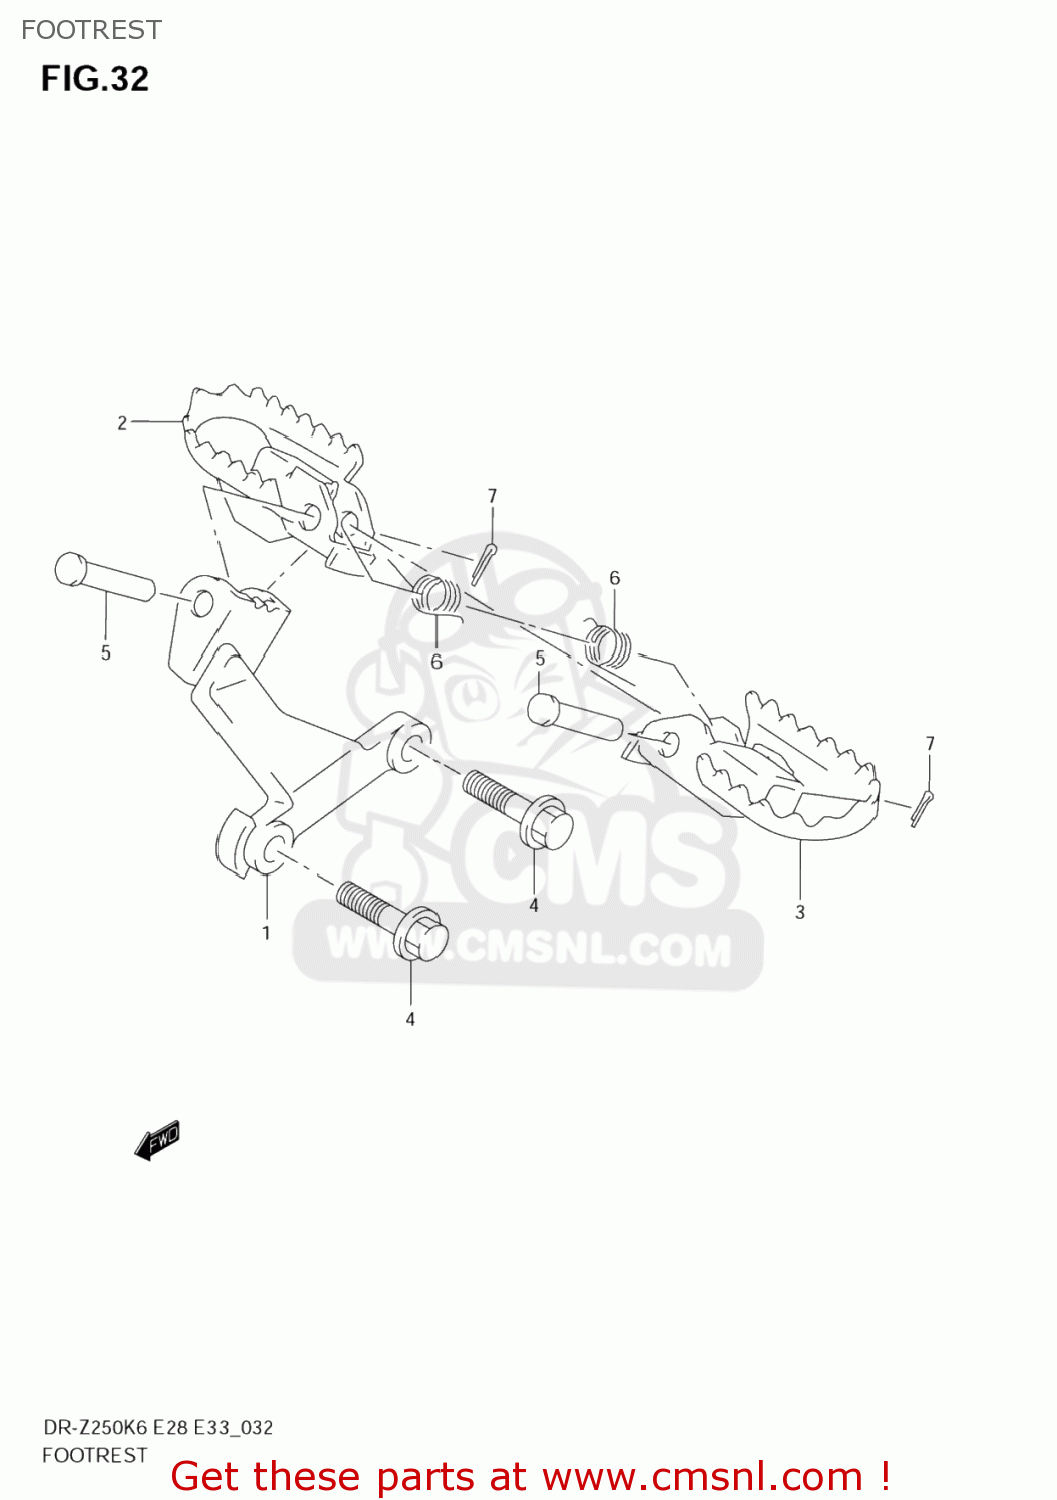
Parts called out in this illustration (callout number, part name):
1	BRACKET,FR FOOTREST,R
2	FOOTREST,FRONT,RIGHT
3	FOOTREST,FRONT,LEFT
4	BOLT(10X40)
5	PIN
6	SPRING
7	PIN
